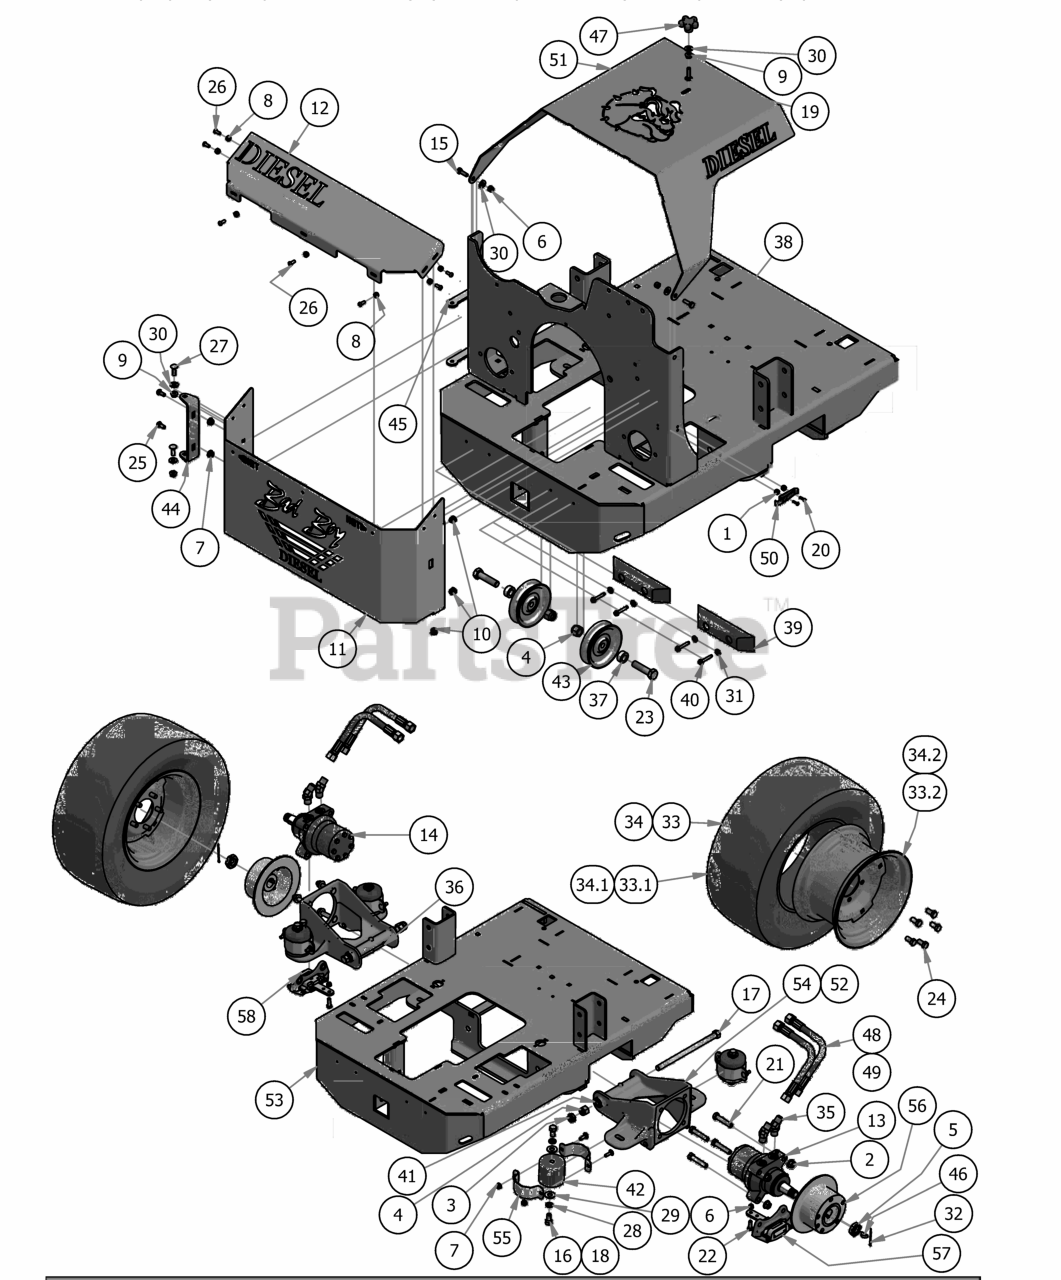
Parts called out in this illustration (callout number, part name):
1	10-24 Nylock Locknut
2	1/2" Flange Nut
3	5/8" Nylock (1/2 Jam)
4	5/8 Std NC Nylock Nut
5	1" Castle Nut for Wheel Motor
6	5/16-18 Nylock Insert Locknut
7	5/16" Nylon Flange Nut
8	1/4 Nylock Nut
9	5/16" Flange Nut
10	5/8 Round Insert
11	Diesel Back Pump Cover 2008 Bottom
12	Diesel Back Pump Cover 2008 Top
13	18cc Parker Wheel Motor- Right
14	18cc Parker Wheel Motor- Left
15	5/16" x 1" Bolt
16	1/2" x 1" Hex Bolt
17	5/8''x10'' Hex Bolt (Grade8)
18	1/2-13 1-1/4 Hex bolt Only On 60" Suspension Kit Wheel Motor
19	5/16" x 1 1/4" Carriage Bolt
20	10-24 X 5/8 BS Button Head Bolt
21	1/2" x 2 1/2" Hex Bolt
22	3/8" x 1" Hex Bolt
23	5/8" x 2 1/2" Grade 5 Hex Bolt (Coarse)
24	1/2" x 1" Hex Bolt
25	5/16-18x3/4 carriage bolt
26	1/4" x 5/8" BS C/S 18-8 SS
27	5/16" x 1" Carriage Bolt
28	1/2" Lock Washer
29	1/2" Washer (Grade 8)
30	.360 ID Plastic Washer
31	1/4" Flat Washer
32	1/8x2-1/4 cotter pin Zinc
33	26 x 12.00 - 12 Tire and Orange Wheel Assembly
33.1	26 x 12.00 - 12 Tire
33.2	12 x 10.5 Wheel AOS Rear
34	26x12-12 Reaper Tire & Wheel Assembly for Diesels
34.1	2019 26x12-12 Reaper Turf Tire
34.2	12 x 10.5 Wheel AOS Rear
35	45 Degree Wheel Motor Fitting -6802-10-10
36	1/4" Drive in Grease Fitting
37	5/8" x 1/" Collar W/One Set Screw
38	Pump Plate Diesel
39	8" Rubber Bumper
40	1/4" x 1 1/2" Self Tapping Screw
41	Brass Bushing
42	Vibration Mount-Blue Dot
43	5 V Idler Pulley - BCVI- 81
44	Back Cover Hinge Bracket
45	Diesel Hinge Tab
46	Woodruff Key
47	5/16" Knob
48	26" Hose Assembly with Adaptors
49	26" Hose Only
50	Steel Pump Cover Latch
51	Diesel Hood 4 Cyl
52	72 Suspension Kit Wheel Motor
53	Outlaw Diesel Frame 2012
54	60 Suspension kit Wheel Motor
55	Isolator Band Clamp
56	Brake Disk
57	XP/AOS Right Brake Caliper
58	XP/AOS Left Brake Caliper
